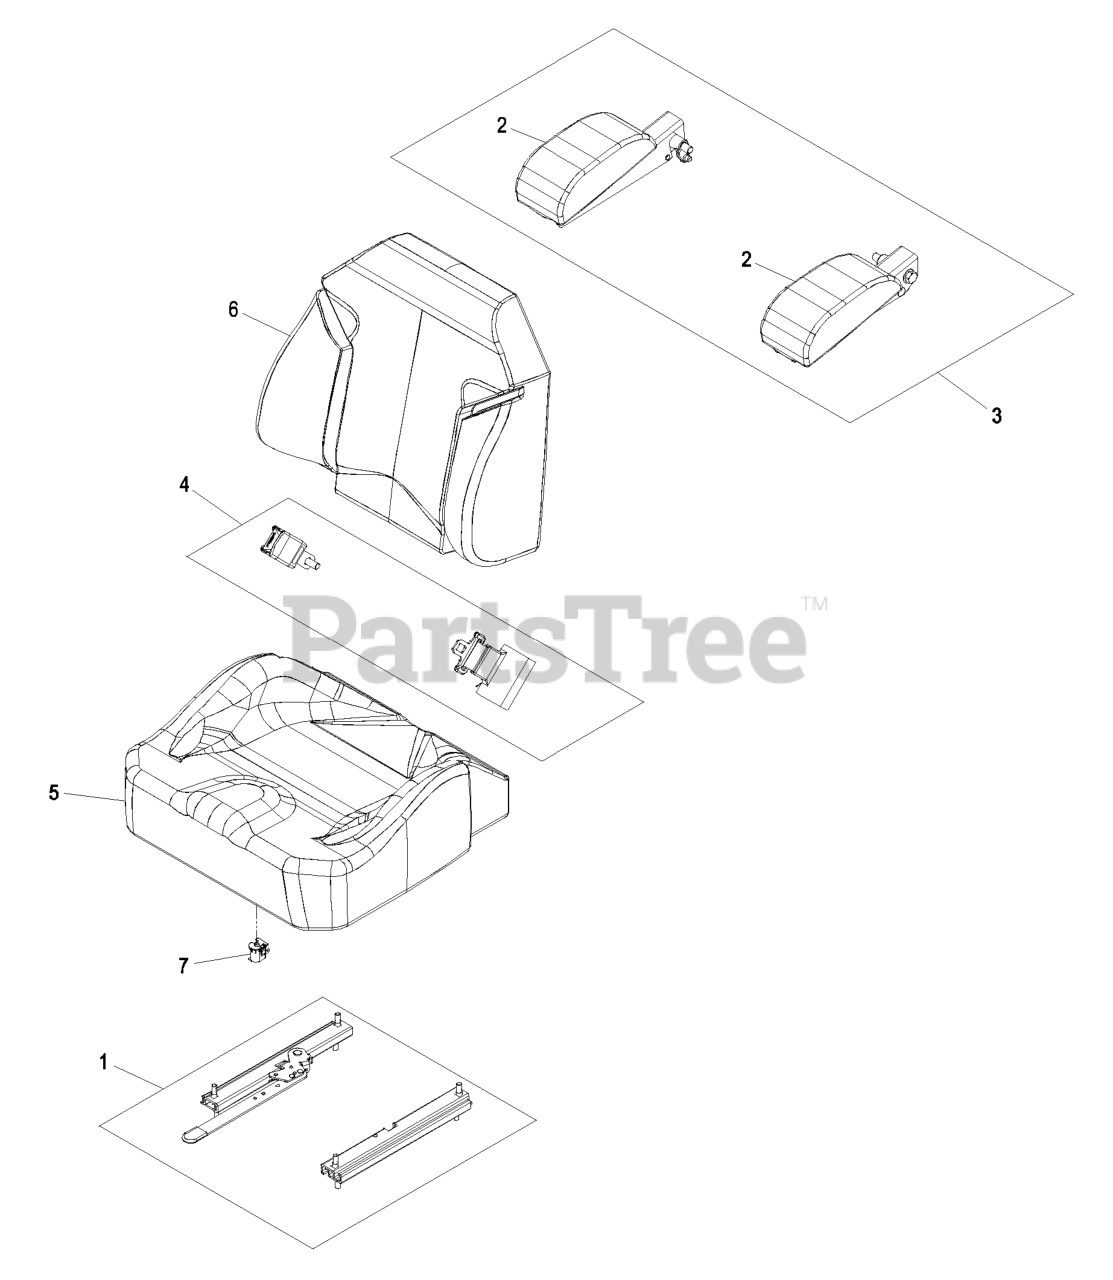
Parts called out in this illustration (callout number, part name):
1	SEAT TRACK SET
2	SET,ARM REST PADS
3	KIT,ARM REST SET
4	SEAT BELT KIT (SHORT)
5	COVER,CUSHION
6	COVER,BACK
7	SWITCH-BAIL
